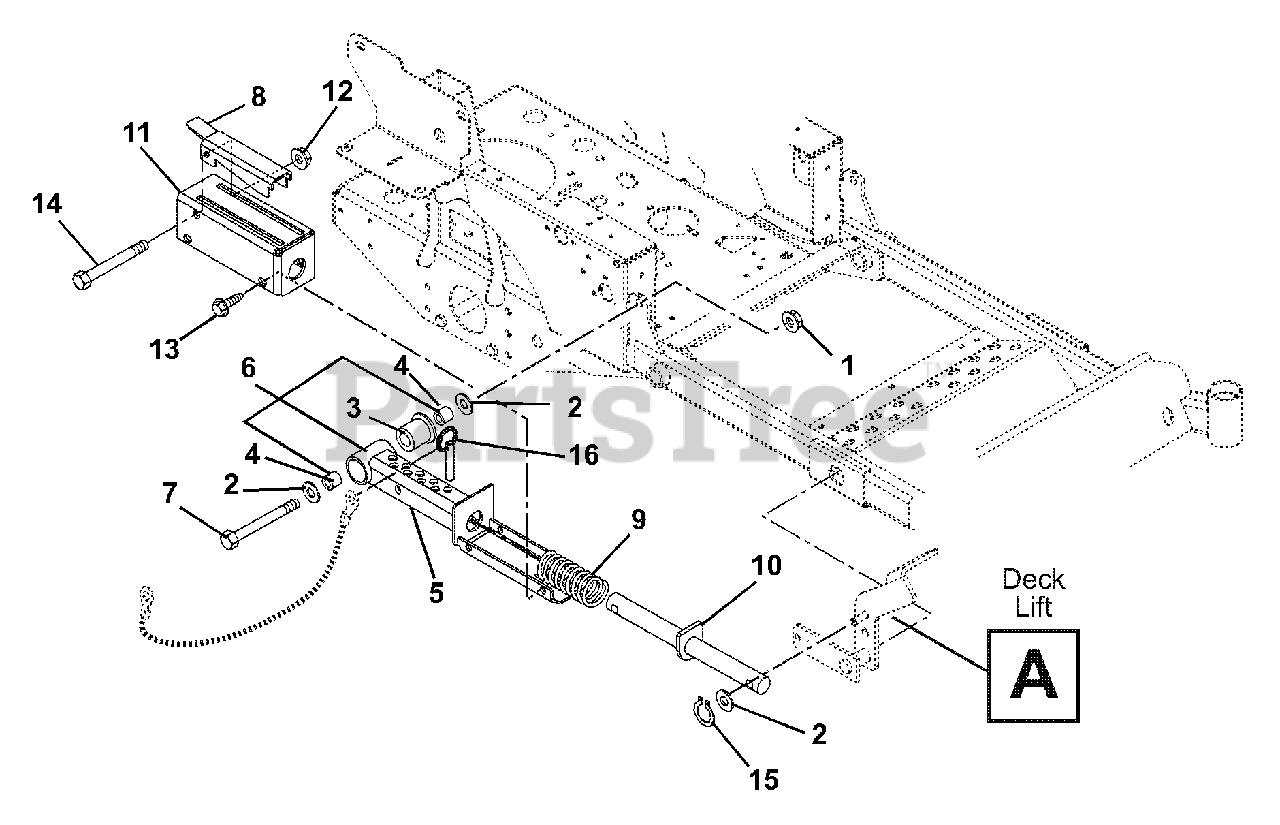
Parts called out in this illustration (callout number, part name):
1	@NUT-LK-TOP-FLG .50-13 YWZC
2	WSHR-FL-STL .531X1.250X.10 YWZ
3	BEARING, PEDESTAL
4	BRG, 1.00 X 1.12 X .75
5	WMT, MECH LIFT
6	ASSM, MECH LIFT
7	@BLT-HEX .50-13X3.75 GR5 YWZC
8	LOCK-UP, MECH LIFT
9	SPR-COMP 1.13X1.48X5.10 WD 165
10	WMT, MECH LIFT SHAFT (.50)
11	WMT, MECH LIFT COVER
12	@NUT-LK-TOP-FLG .38-16 YWZC
13	@SCR-TAP .38-16X.50 HWH TR YWZ
14	@BLT-HEX .38-16X3.25 GR5 YWZC
15	RG-RTNG-EXT .500X.050 (SNAP)
16	PIN, SPRING BALL .375OD X 1.50
